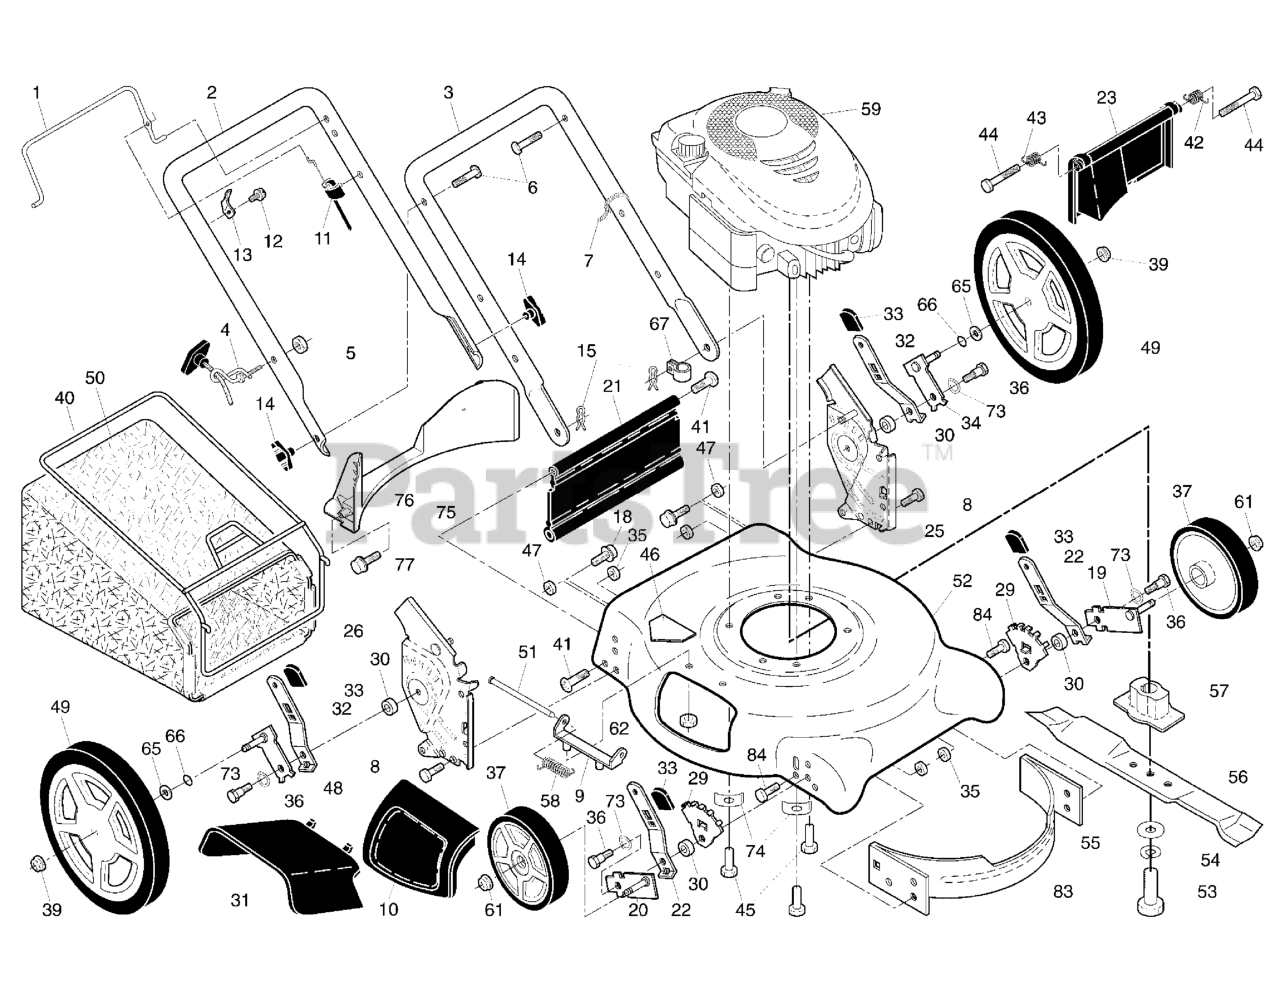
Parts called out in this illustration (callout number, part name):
1	Control Bar
2	Upper Handle
3	Lower Handle
4	Rope Guide
5	Nut, Hex
6	Handle Bolt
7	Wire Tie
8	Bolt, Hex Head 5/16-18 x 3/4
9	Hinge Bracket
10	Mulcher Door
11	Engine Zone Control Cable
12	Hex Washer Head Screw
13	Up-Stop Bracket
14	Handle Knob
15	Hairpin Cotter
18	Screw 1/4-20 x 3/8
19	Axle Arm Assembly, Front, LH
20	Axle Arm Assembly, Front, RH
21	Kit, Rear Skirt
22	Selector Spring, Front
23	Rear Door Assembly
25	Handle Bracket Assembly, LH
26	Handle Bracket Assembly, RH
29	Wheel Adjusting Bracket
30	Spacer
31	Discharge Defl ector
32	Selector Spring, Rear
33	Selector Knob
34	Axle Arm Assembly, Rear, LH
35	Locknut, Hex 5/16-18
36	Shoulder Bolt 5/16-18
37	Wheel & Tire Assembly, Front
39	Flanged Locknut, Hex
40	Frame, Grassbag
41	Hinge Screw
42	Spring, Rear Door, LH
43	Spring, Rear Door, RH
44	Bolt, Rear Door
45	Screw, Hex Head, Threaded, Rolled, 3/8-16 x 1
46	Danger Decal
47	Nut, Hex
48	Axle Arm Assembly, Rear, RH
49	Wheel & Tire Assembly, Rear
50	Grassbag
51	Hinge Rod
52	Kit, Lawn Mower Housing
53	Screw, Hex Head, 3/8-24 x 1-3/8, G8
54	Helical Lockwasher
55	Hardened Washer
56	21" Blade
57	Blade Adapter
58	Hinge Spring
59	* Engine, Briggs & Stratton
61	Nut, Hex
62	Locknut, Hex 1/4-20
65	Washer, Flat
66	O-Ring
67	Clip, Cable
73	Washer, Curved
74	Washer, Special, Engine
75	Kit, Rear Baffl e
76	Baffle, Rear
77	Screw, Rear Baffl e
83	Baffle, Front
84	Screw, Front Baffle
